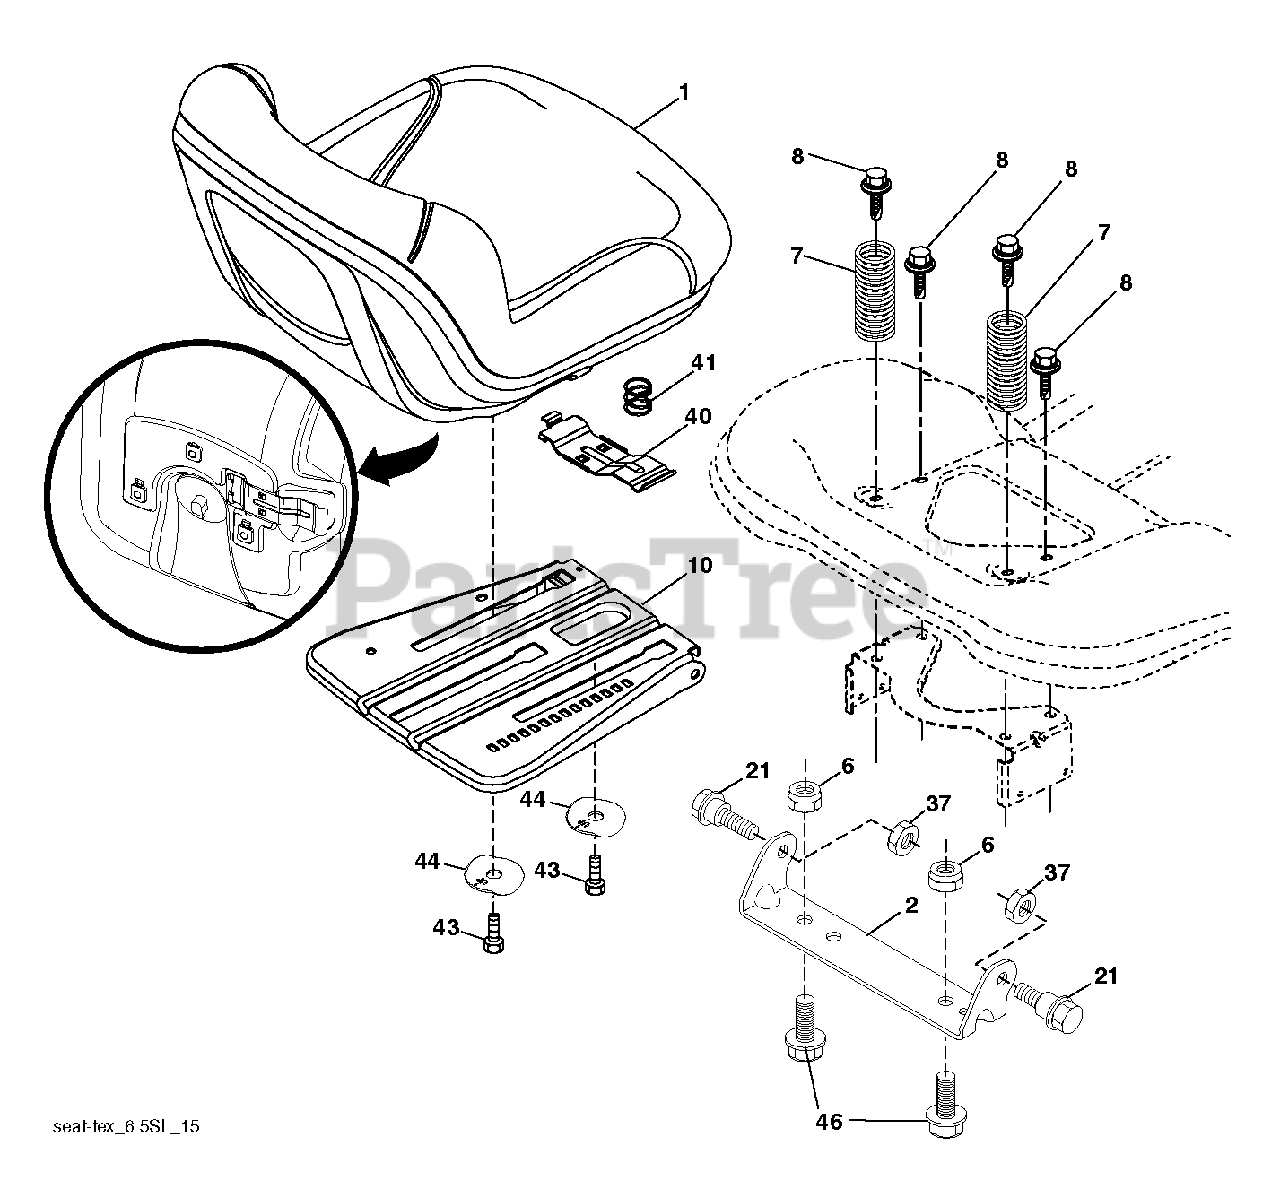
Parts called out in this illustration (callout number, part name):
1	SEAT.TH150.MS498.GRY.HUSQ.TEX
2	BRKT.PIVOT.FENDER
6	NUT
7	SPRING.COMPRESS.SEAT.
8	BOLT, 5/16-18 X 1 3/4
10	Seat Slide Plate, Pnt
21	BOLT.5/16-18X5/8.SHOULDER
37	NUT.71038.31-18.HEX.NYLOCK
40	HANDLE.SLIDE.SEAT.TEX.BLACK
41	SPRING.LATCH.SEAT.TEX
44	Winged Washer, 38Id 1
46	BOLT.3/8-16X1;1.25OD.WSHR.SEMS
